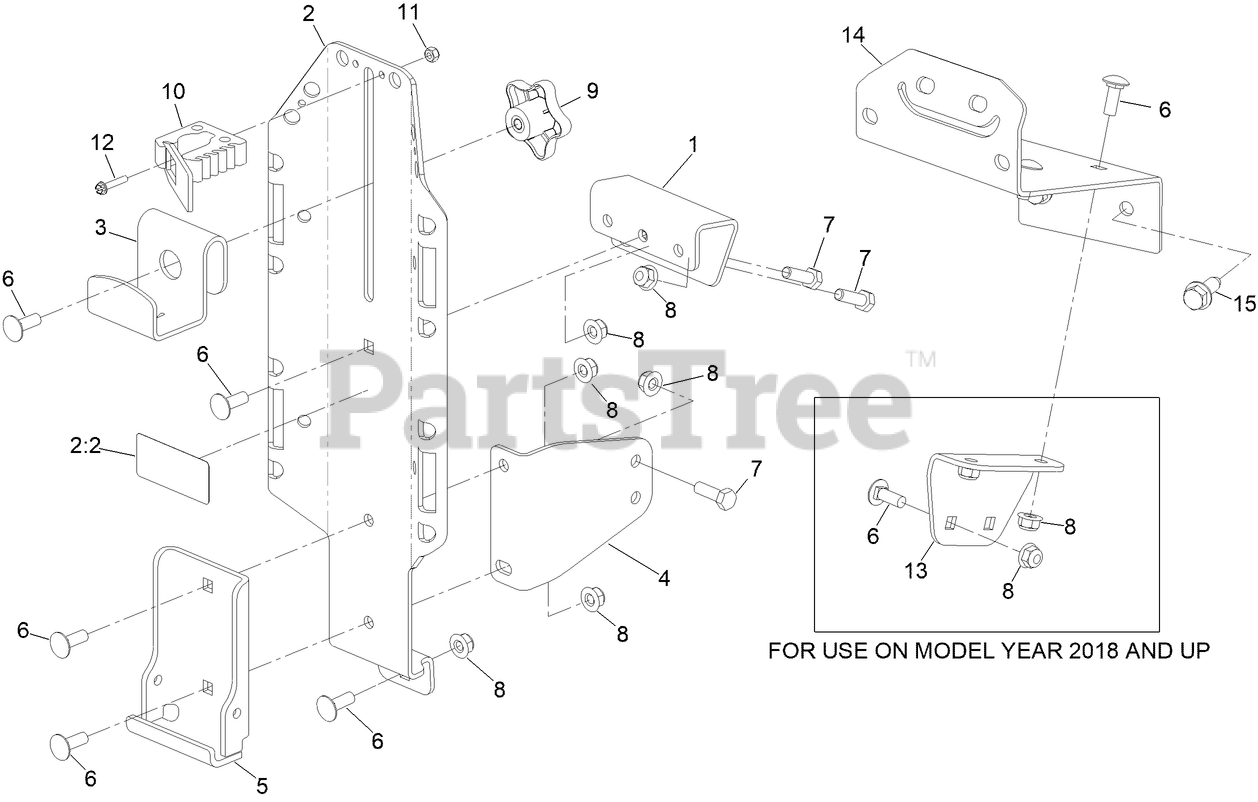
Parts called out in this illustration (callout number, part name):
1	MOUNT-BUCKET, UPPER
2	MOUNT BRACKET ASM
2:2	DECAL-WEIGHT, MAXIMUM
3	BRACKET-TOP
4	BRACKET-SUPPORT, LOWER
5	BRACKET-SUPPORT, HINGE
6	BOLT-CARR
7	SCREW-HH
8	NUT-HF, NI
9	KNOB-HANDLE
10	CLAMP-QUICK FIST, MINI
11	NUT-LOCK
12	SCREW-SHWH
13	BRACKET-SUPPORT, INNER
14	BRACKET-SUPPORT, POD (LH)
15	SCREW-FORMING, THREAD
